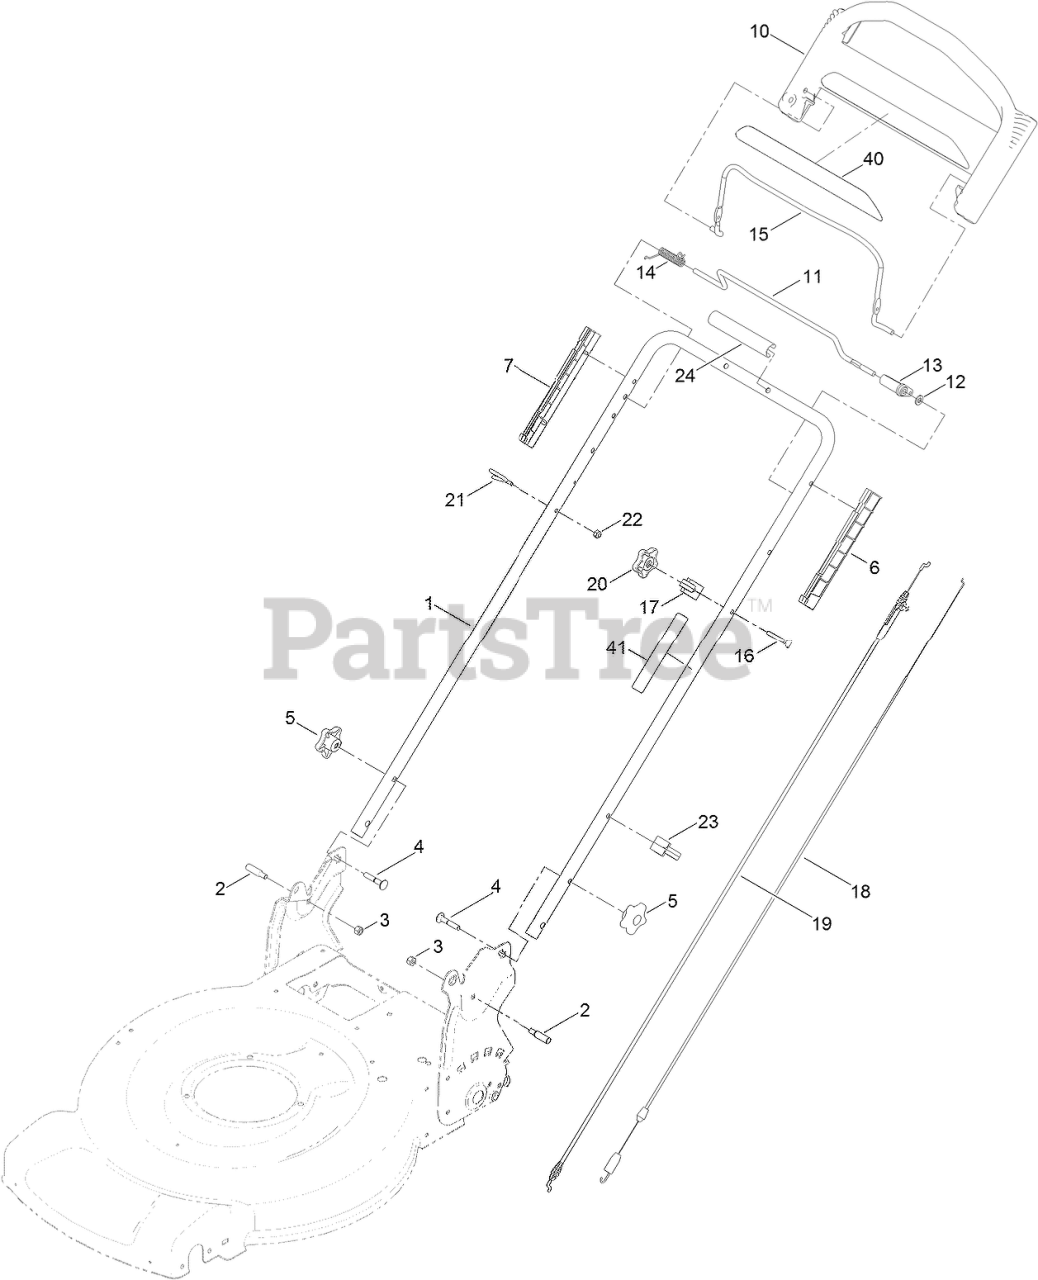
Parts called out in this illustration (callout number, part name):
2	BOLT-SHOULDER
3	NUT-LOCK, NI
4	SCREW-CARR
5	KNOB-HANDLE
6	GUIDE-LH
7	GUIDE-RH
10	HANDLE-CONTROL
12	WASHER-PLAIN
13	LEVER-TRACTION
15	BAIL-BRAKE
16	SCREW
17	ANCHOR-CABLE
18	CABLE-TRACTION
19	CABLE-BRAKE
20	KNOB-HANDLE, LOCKING
21	GUIDE-ROPE
22	NUT-LOCK, NI
23	GUIDE-CABLE
24	HANDLE-COVER
40	DECAL-HANDLE
41	DECAL-TRACTION, ADJUST
